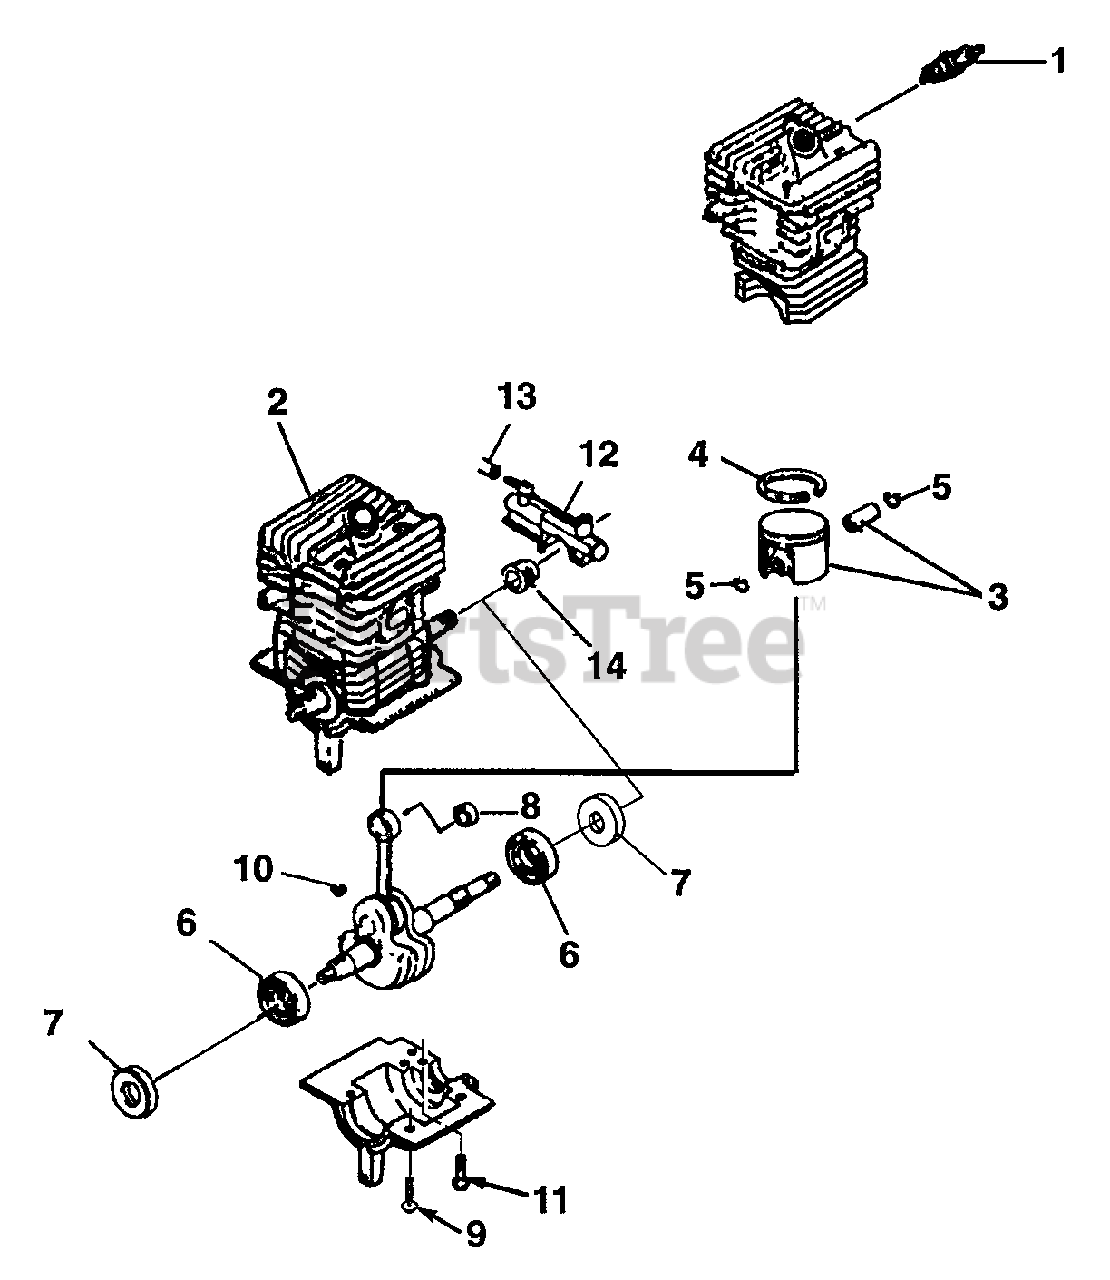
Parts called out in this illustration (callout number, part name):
1	SPARK PLUG (RCJ6Y)
2	SHORT BLOCK
3	PISTON & PIN
4	RING, PISTON ASSEMBLY
5	RING, WRIST PIN RETAIN.
6	BEARING & CAP, CRANKSHAFT
7	SEAL, SHAFT
8	BEARING, NEEDLE
9	SCREW, Hex Hd. (12-24 X 7/8")
10	KEY, WOODRUFF
11	SCREW, FIL. HD. (8-32 X 5/8") (OIL PUMP)
12	OIL PUMP
13	TUBING, OIL
14	WORM GEAR, LEFT HAND
